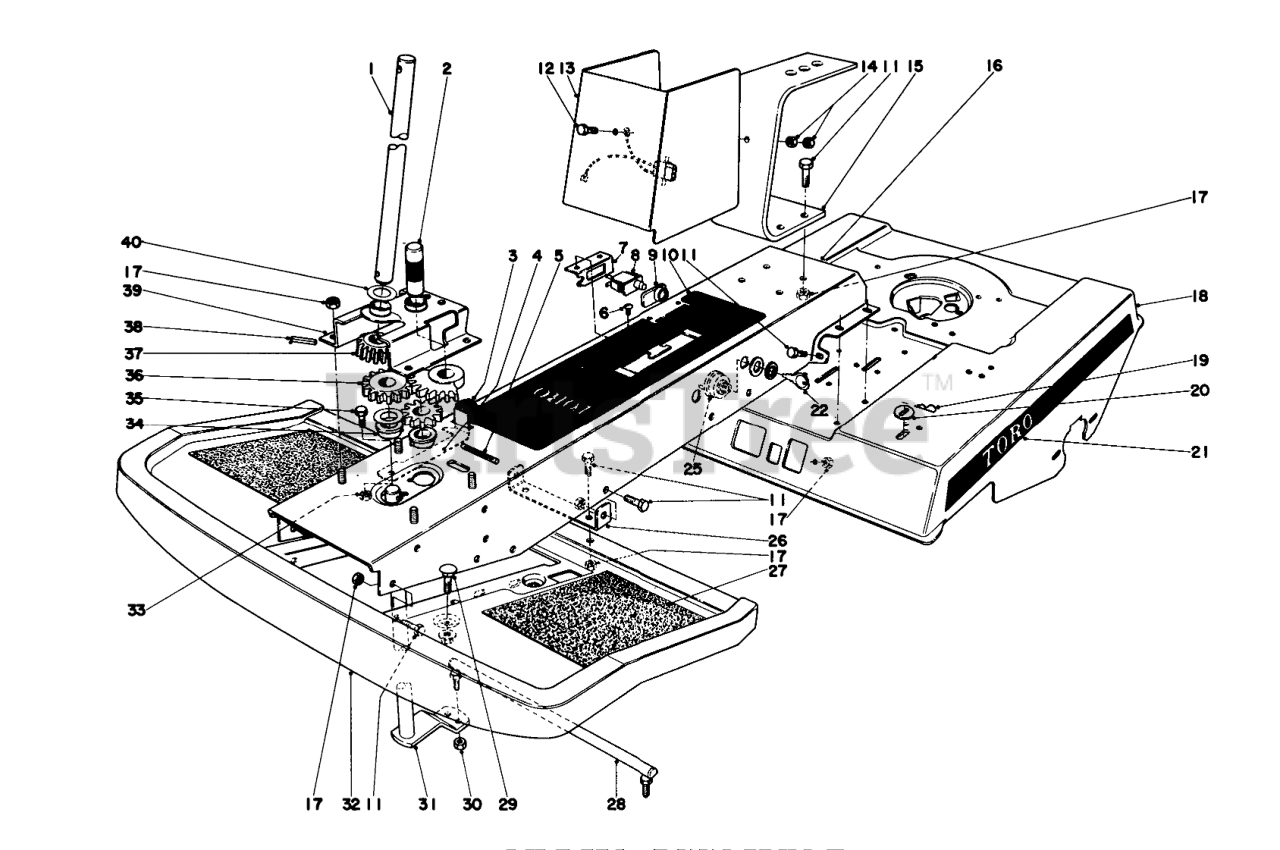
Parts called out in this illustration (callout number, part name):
1	Shaft Upper
2	Steering Idler Ass-y.
3	Parking Brake Tip
4	Parking Brake Spring
5	3/16 X 1-1/2 GRVE PIN
6	Nut-Clinch
7	Switch Bracket
8	Switch
9	Boot Switch
10	Throttle Control Decal
11	SCREW-HH
12	SCREW-HH
13	Cover Seat
14	NUT-LOCK, CONE
15	Seat Spring
16	Center Frame Member
17	NUT-LOCK, CONE
18	Engine Mounting Frame
19	PIN-COTTER
20	Washer
21	Decal L.H.
22	Key
25	Switch
26	Support
27	Foot Tread
28	Ball Joint
29	SCREW-CARR
30	NUT-LOCK, NI
31	Shaft
32	Foot Rest
33	NUT-LOCK, CONE
34	Bushing
35	SCREW-HH
37	STEERING PINION
38	PIN-ROLL, SLOTTED
39	Bracket Steering Support
40	Washer
